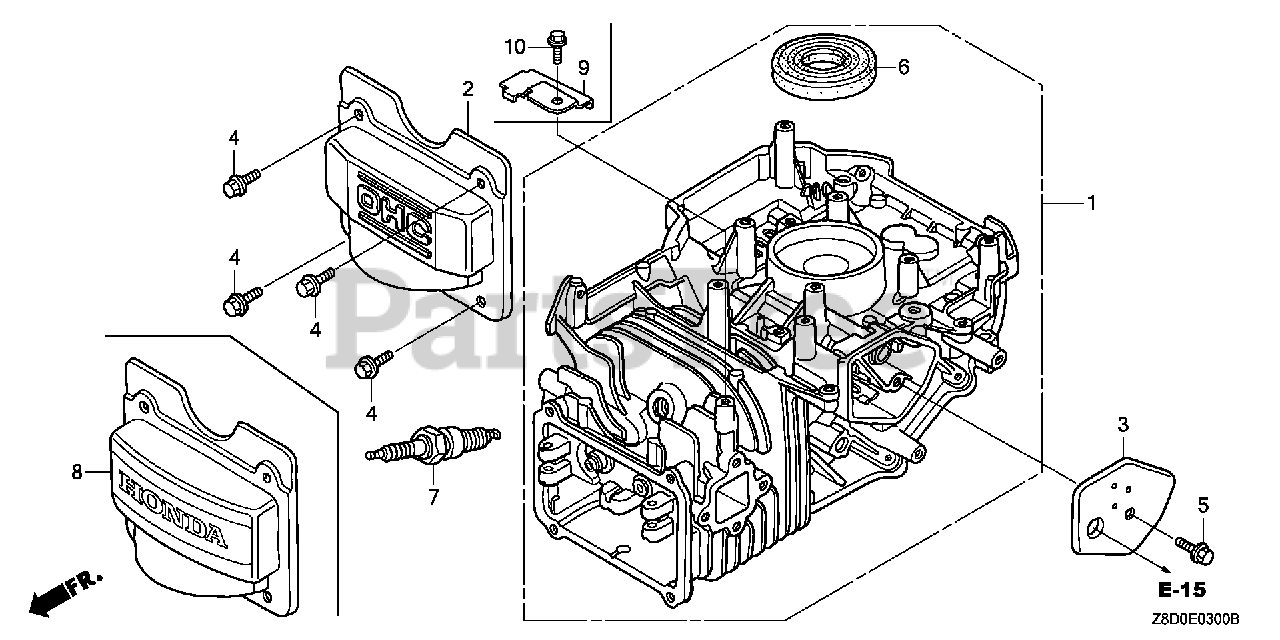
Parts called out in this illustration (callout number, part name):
1	CYLINDER ASSY.
3	COVER, BREATHER (BREATHER VALVE ASSY.)
4	BOLT, FLANGE (6X12) (CT200)
5	BOLT, FLANGE (6X14) (CT200)
6	OIL SEAL (25.4X62X6)
7	SPARK PLUG (BPR6ES) (NGK)
8	COVER, HEAD
